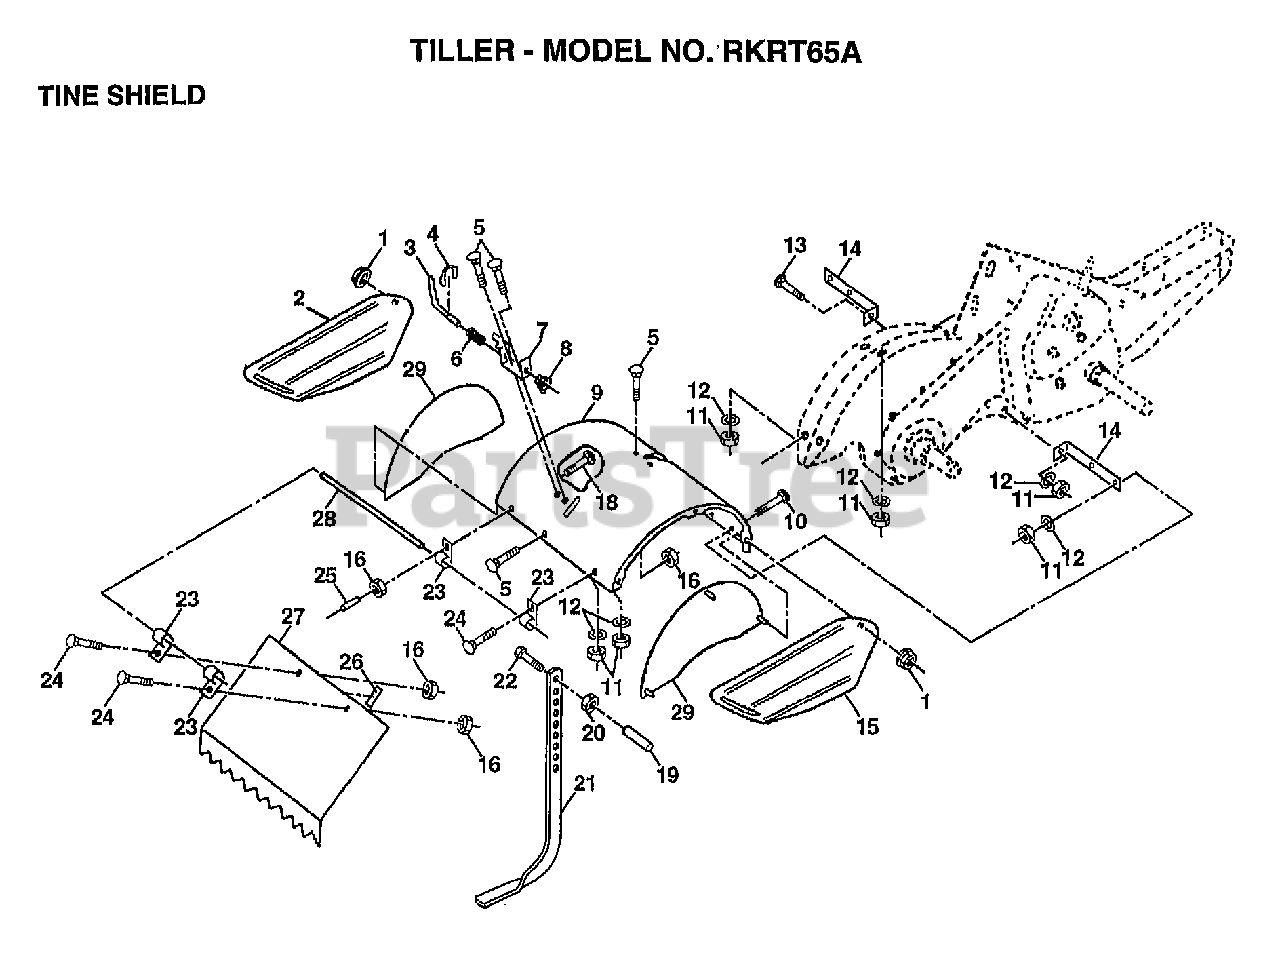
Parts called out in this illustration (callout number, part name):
1	NUT
2	SHLD.SIDE.OUTER.L
3	STAKE PIN TI
4	KLIP RING TI
5	BOLT
6	SPRING TI
7	LATCH BRACKET TI
8	SPRING CRT
9	SHIELD TINE
10	BOLT
11	NUT.HEX.5/16-18
12	LOCKWASHER
13	BOLT
14	"BRACKET,SHIELD"
15	SHLD.SIDE.OUTER.R
16	NUT
18	BOLT
19	GRIP CRT
20	NUT.HEX.3/8-16UNC
22	BOLT
23	HINGE CRT
24	BOLT
25	VINYL CAP TI
26	PAD IDLER TI
27	"SHIELD,LEVEL"
28	PIN HINGE
29	SHIELD TINE
30	LOCKNUT TI
